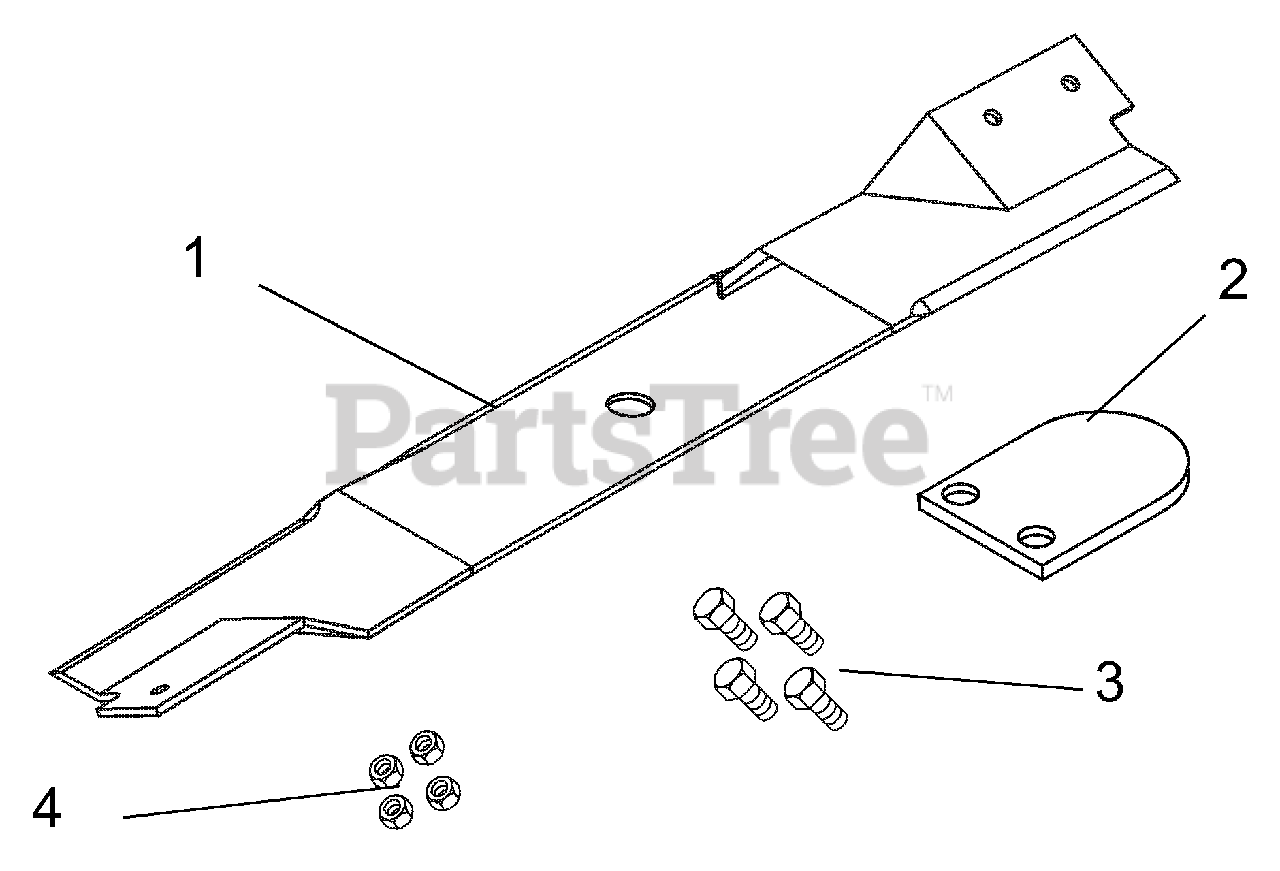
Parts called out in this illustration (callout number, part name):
1	BLADE, 50" MOWER HI-LIFT HOLES
2	VANE, BLADE
3	BLT-HEX .31-24X.75 GR8 YWZC
4	NUT-CTRLK .31-24 YWZC
